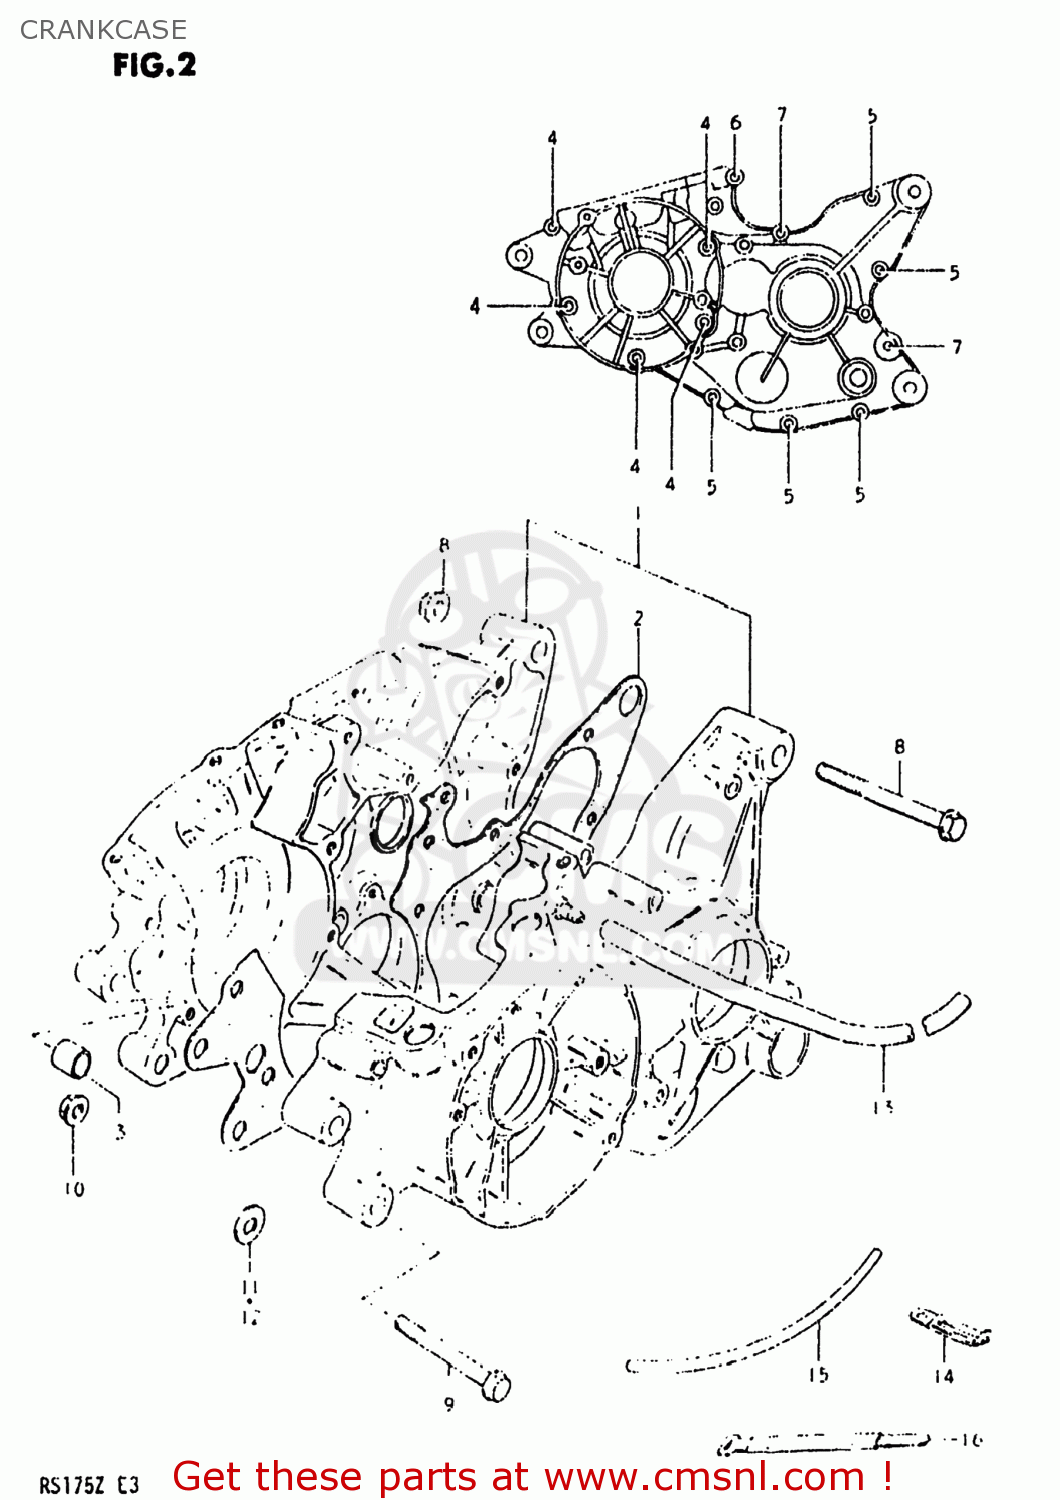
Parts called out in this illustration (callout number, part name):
1	CRANKCASE SET
2	GASKET,CRANKCASE (MCA)
3	PIN
4	SCREW (6X45)
5	SCREW
6	SCREW
7	SCREW 6X60
8	BOLT (8X95)
9	BOLT(8X67)
10	NUT
11	WASHER
12	WASHER
13	HOSE,FUEL
14	CLAMP
15	HOSE
16	CLAMP L:110
